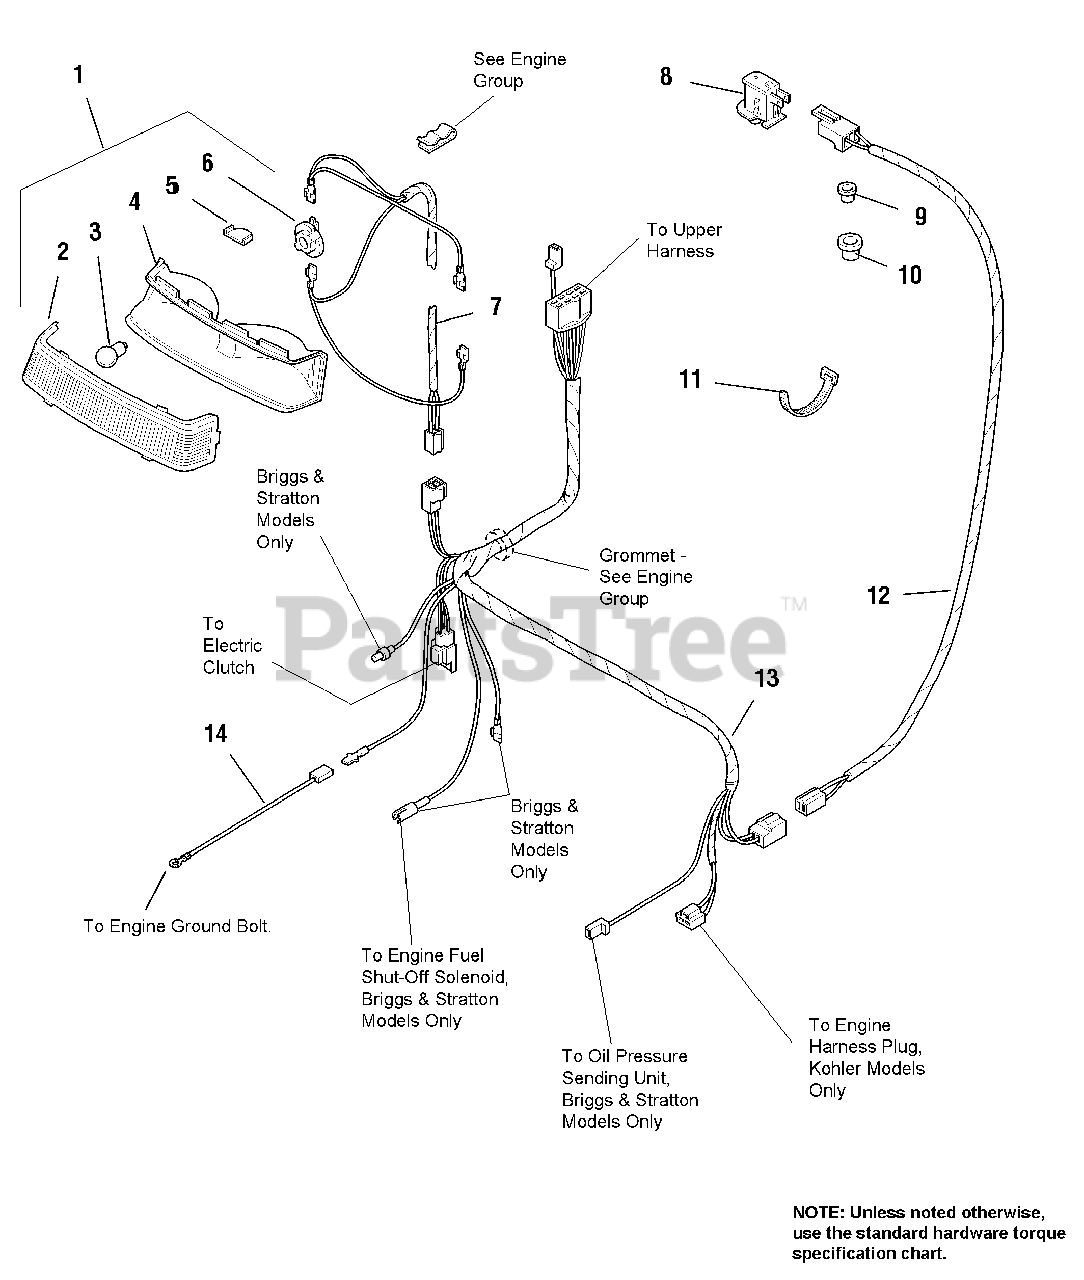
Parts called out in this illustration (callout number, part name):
1	HEADLIGHT ASSY.
2	LENS, Headlight
3	BULB, Headlight, 12.8V
4	BEZEL, Headlight
5	HEAT SHIELD
6	SOCKET, Bulb
7	WIRE ASSY., Headlight
8	SWITCH, Seat, Operator Present
9	BUSHING, Snap, Small
10	BUSHING, Snap, Large
12	WIRE ASSY., Seat Switch
13	WIRE HARNESS, Lower
14	WIRE ASSY., Engine Ground
